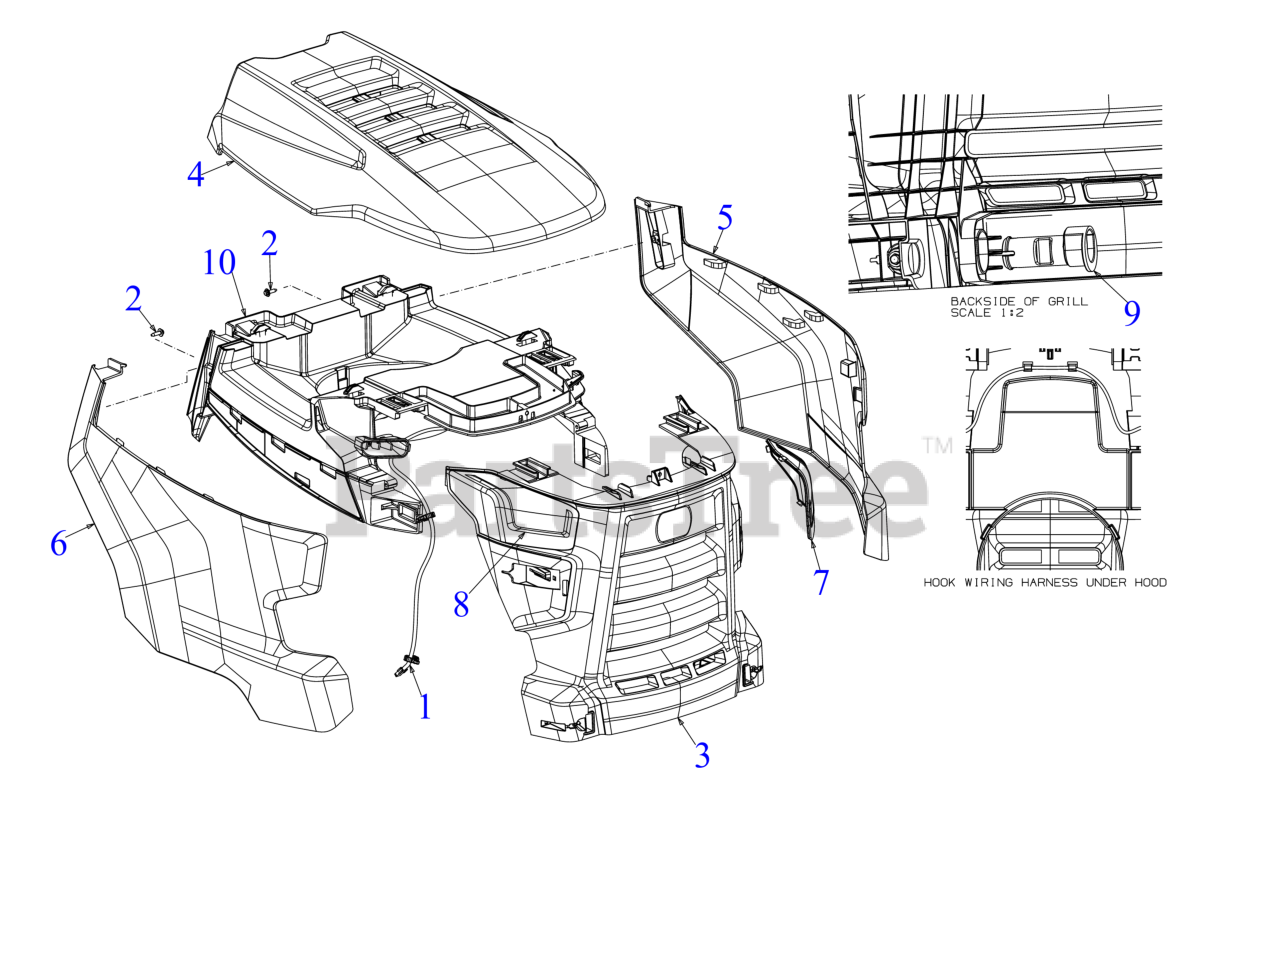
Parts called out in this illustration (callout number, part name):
1	HEADLIGHT HARNESS (W/LED)
2	SCREW 1/4-10 x .750
3	FRONT GRILLE (STYLE C)
4	HOOD TOP (YELLOW)
5	SIDE PANEL (LH)
6	SIDE PANEL (RH)
7	LED HEADLIGHT LENS (LH)
8	LED HEADLIGHT LENS (RH)
9	HOOD PIVOT PIN
10	PLENUM/HOOD FRAME W/O LABEL
